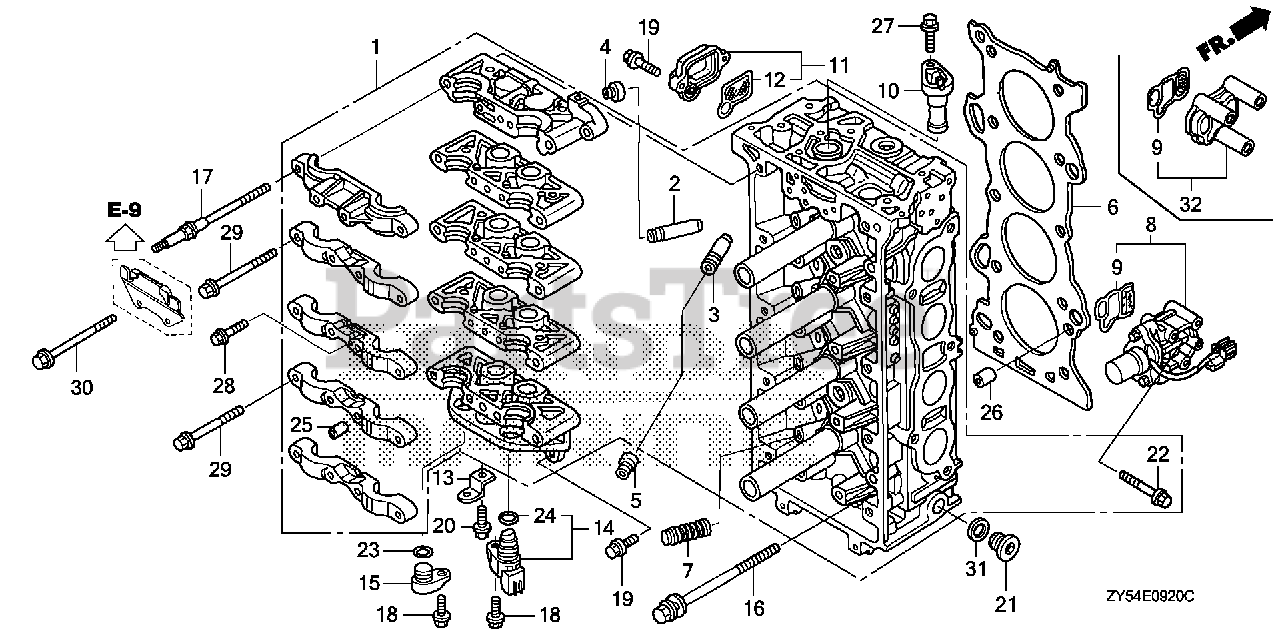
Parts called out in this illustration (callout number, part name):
1	CYLINDER HEAD KIT *NH8* (DARK GRAY)
1	CYLINDER HEAD KIT *N
2	GUIDE, VALVE (OVER SIZE)
3	GUIDE, EX. VALVE (OVER SIZE)
4	SEAL A, VALVE STEM (NOK)
5	SEAL B, VALVE STEM (NOK)
6	GASKET, CYLINDER HEAD
8	COVER ASSY., OIL PASSAGE
9	FILTER ASSY., SPOOL VALVE
10	PLUG, VTC HOLE
11	STRAINER ASSY., VTC *NH8* (DARK GRAY)
12	FILTER ASSY., VTC
13	BRACKET F, CLIP
14	SENSOR ASSY., TDC
15	PLUG, TDC HOLE
16	BOLT-WASHER (11X155)
17	BOLT A, HEAD COVER
18	BOLT, FLANGE (6X16)
19	BOLT, FLANGE (6X20)
20	BOLT, FLANGE (6X14)
21	BOLT, SEALING (20MM)
22	BOLT, FLANGE (6X52)
23	O-RING (15X1.9)
24	O-RING (15X1.9)
25	PIN A, DOWEL (10X16)
26	PIN A, DOWEL (14X20)
27	BOLT, FLANGE (6X20)
28	BOLT, FLANGE (6X32)
29	BOLT, FLANGE (8X90)
30	BOLT, FLANGE (8X110)
31	WASHER, DRAIN PLUG (20MM)
32	COVER ASSY., OIL PASSAGE
